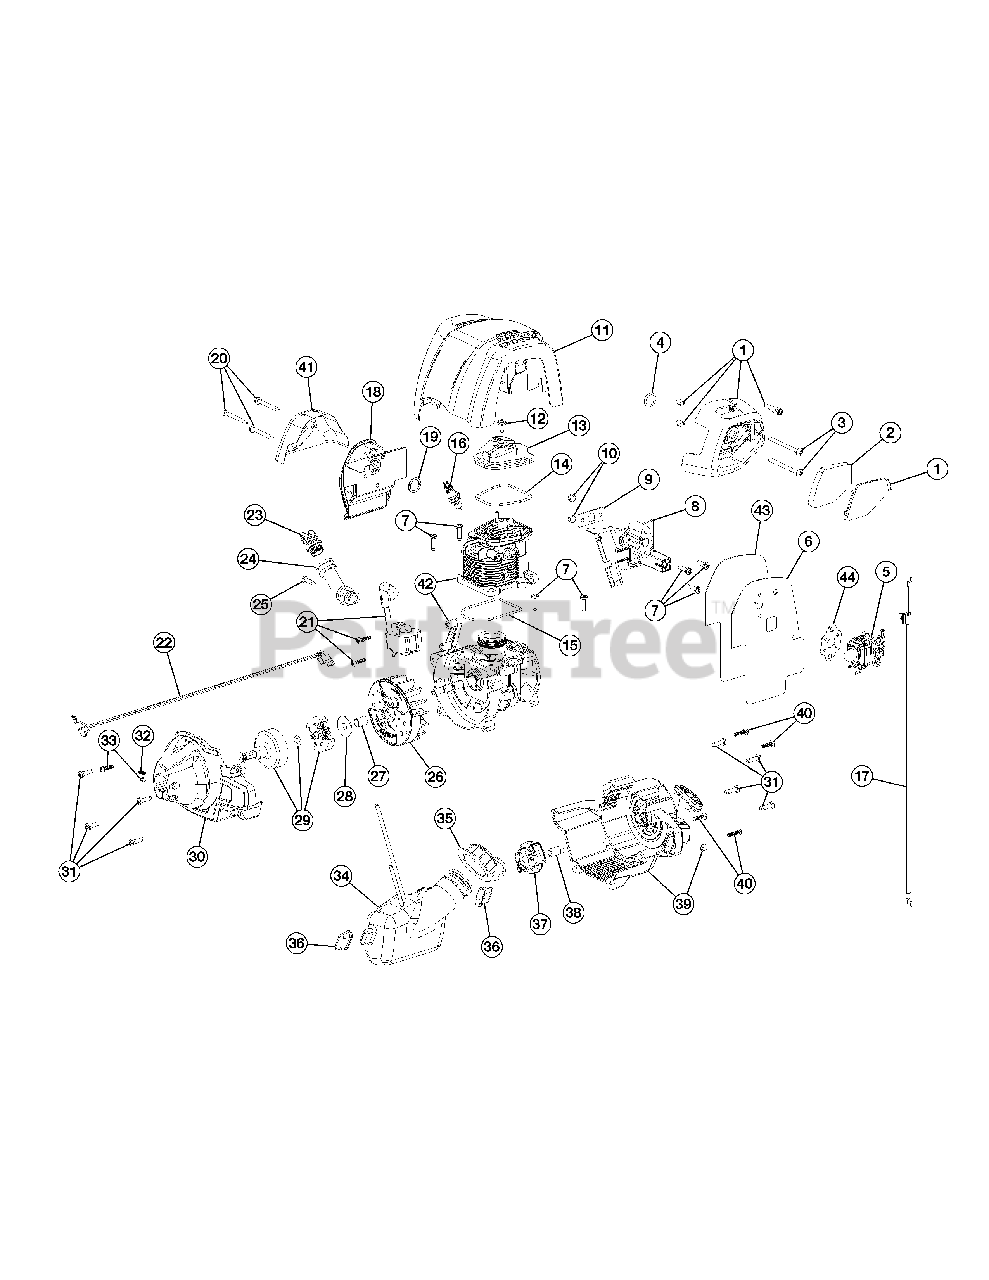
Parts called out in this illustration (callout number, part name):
1	Air Cleaner Assembly (Incl. 2 & 3)
2	Air Filter
4	Carburetor O-Ring
5	Carburetor
6	Carburetor Baffle
7	Screw
9	Insulator Gasket
11	Engine Cover
13	Valve Cover
14	Valve O-Ring
15	Cylinder O-Ring
16	Spark Plug
17	Throttle Cable
18	Muffler Assembly
19	Muffler Gasket
20	Muffler Bolt
21	Module Assembly
22	Lead Wires
23	Oil Plug Assembly
24	Oil Fill Tube Assembly (Incl. 25)
28	Clutch Washer
29	Clutch Assembly
30	Clutch Cover Assembly
32	Anti-rotation Screw
33	Clamp Screw & Nut
36	Fuel Tank Pad
37	Pawl Assembly
38	Electric Start Adapter
39	Starter Cover Assembly
41	Muffler Shield
42	Short Block Assembly
43	Heat Shield
